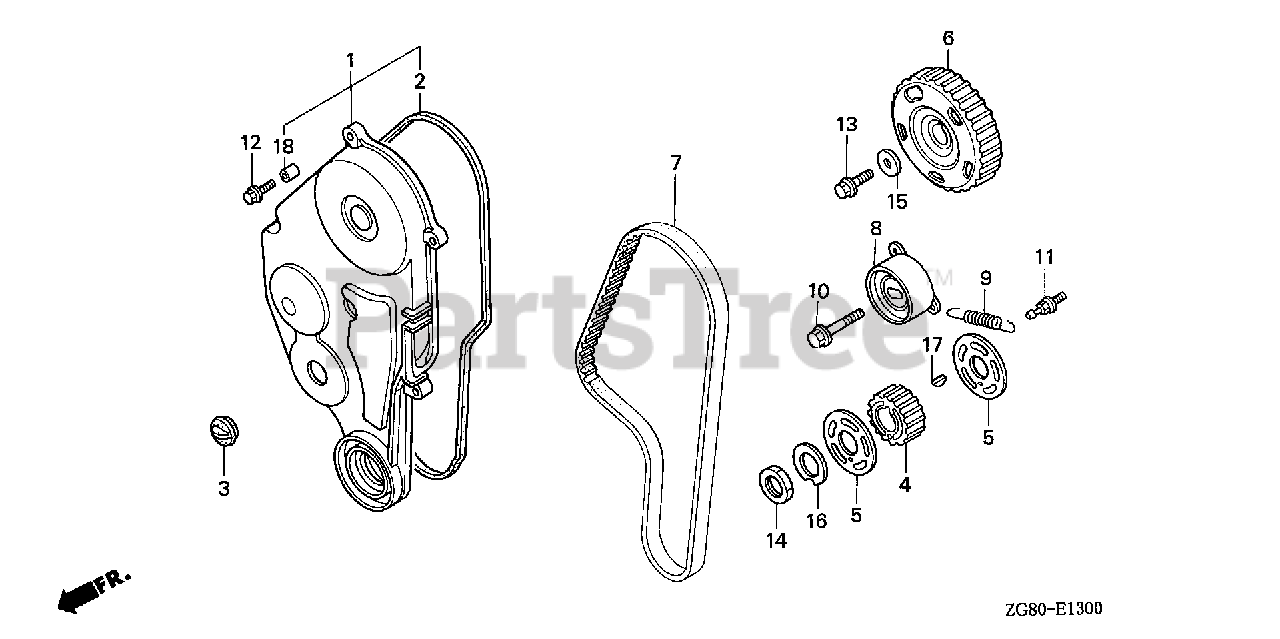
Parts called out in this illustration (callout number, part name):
1	COVER, TIMING BELT
2	GASKET, TIMING BELT COVER
3	GROMMET, TIMING BELT COVER HOLE
4	PULLEY, TIMING BELT DRIVE
5	PLATE, TIMING BELT GUIDE
6	PULLEY, TIMING BELT DRIVEN
7	BELT, TIMING
8	TENSIONER, TIMING BELT
9	SPRING, TIMING BELT ADJUSTING
10	BOLT A, TENSIONER
11	BOLT, TIMING BELT ADJUSTER SPRING (NAGOYA RASHI)
12	BOLT, FLANGE (6X20) (CT200)
13	BOLT, FLANGE (8X22)
14	NUT, LOCK (27MM)
15	WASHER, SPECIAL (28X8.5X4.0)
16	WASHER, LOCK (27MM)
17	KEY, SPECIAL (16X15)
18	COLLAR, CONTROL LEVER
